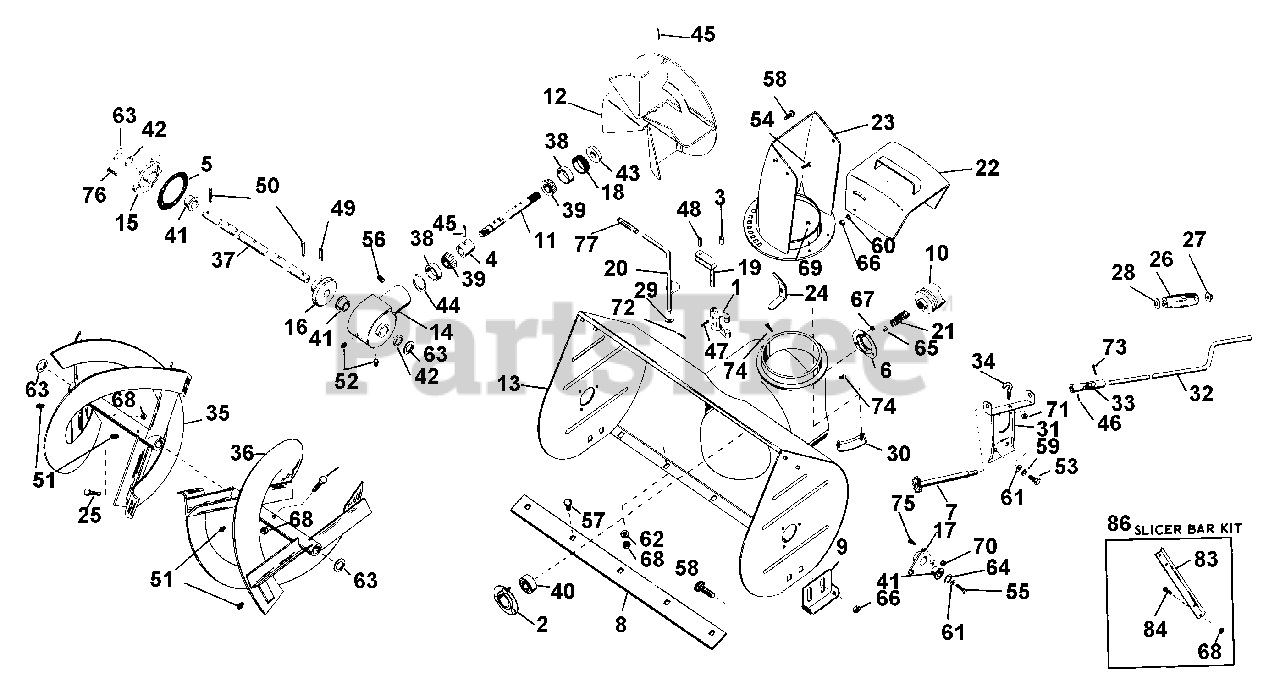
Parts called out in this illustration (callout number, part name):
1	CLUTCH FORK
2	BEARING FLANGE
4	BEARING SPACER
6	BEARING FLANGE
7	CONTROL SPROCKET
8	SCRAPER BLADE 24"
9	RUNNER
10	JAW CLUTCH
11	HELICON PINION SHAFT
13	BLOWER HOUSING
14	CASE, GEAR - C.I.
15	GEAR CASE FLANGE
16	HELICON GEAR - 41 TOOTH
17	BEARING SUPPORT
18	ADJUSTMENT PLUG
19	FORK SHAFT
20	FORK CAM
21	SPRING
22	DEFLECTOR CHUTE
23	DISCHARGE CHUTE
24	WING NUT
25	SHEAR BOLT YWZC
27	CAP, 3/8 ROD YWZC
28	FASTENER
29	WAVE WASHER .406X.750X.063FH
30	CHUTE CLAMP
31	CHUTE CNTL BRACKET
32	CHUTE CNTL CRANK
33	UNIVERSAL JOINT
35	R H RAKE
36	L H RAKE
37	FRONT GEAR SHAFT
38	BRG-CUP 1.781X.475
39	BRG-CONE .750X.61
40	BRG-BALL .750X1.750X.50
41	BSHG-FLG 1.000X1.12X.62X1.50BR
42	SEAL 1.000X1.312X.150
43	SEAL .750X1.499X.225
44	RG-RTNG INT 1.781 HSG X.062
45	PIN-ROLL .250X1.25
46	PIN-ROLL .125X1.00
47	PIN-ROLL .250X1.25
48	PIN-ROLL .250X1.25
49	PIN-ROLL .313X1.38
50	PIN-ROLL .188X1.25
51	HYDRAULIC DRIVE FITTING
52	PIPE PLUG
53	BLT-HEX .31-18X.63 PL GR 2
54	BLT-HEX .31-18X.63 PL GR 2
55	BLT-HEX .31-18X.63 PL GR 2
56	SCR-SET .38-16X.50 SKHCUP OH
57	BLT-RDHDSQSHNK .31-18X.50 YZ
58	BLT-RDHDSQNK .38-16X.75 SHT PL
59	WSHR-LK .312X.097 PL HVY
60	WSHR-LK .375X.115 HVY PL
61	WSHR-LK .500X.151 HVY PL
62	WSHR-FL-STL .38X.875X.083 PL
63	BRG-CUP 2.328X.465
64	BRG-CONE 1.25X.66
65	BRG-CUP 3.346X.532
66	NUT-LK-CTR .375-16 GR A PL
67	NUT-LK-CTR .250-20 PL
68	NUT-LK .312-18 GR A PL
69	NUT-KEPS 10-24 PL
70	NUT-LK-FLG .250-20 PL
71	NUT-LK .312-18 GR A PL
72	PIN-COTR .12X1.0 PL
73	PIN-COTR .09X.75 PL
74	BLT-SCRHFWH .38-16X.50 PL
75	SCR-SLTR-SERNK .25-20X.62 PL
76	BLT-SERHFWH .25-20X.75 PL
78	Serial Number Label
79	DISCHARGE CAUTION LABEL
80	DISCHARGE CAUTION LABEL
81	MOWER IN-OUT LABEL
82	MOWER IN-OUT LABEL
83	CUTTER BAR
84	BLT-RDHDSQSHNK .31-18X.50 YZ
85	NUT-LK .312-18 GR A PL
86	Slicer Bar Kit(Inc. 83,84,85)
